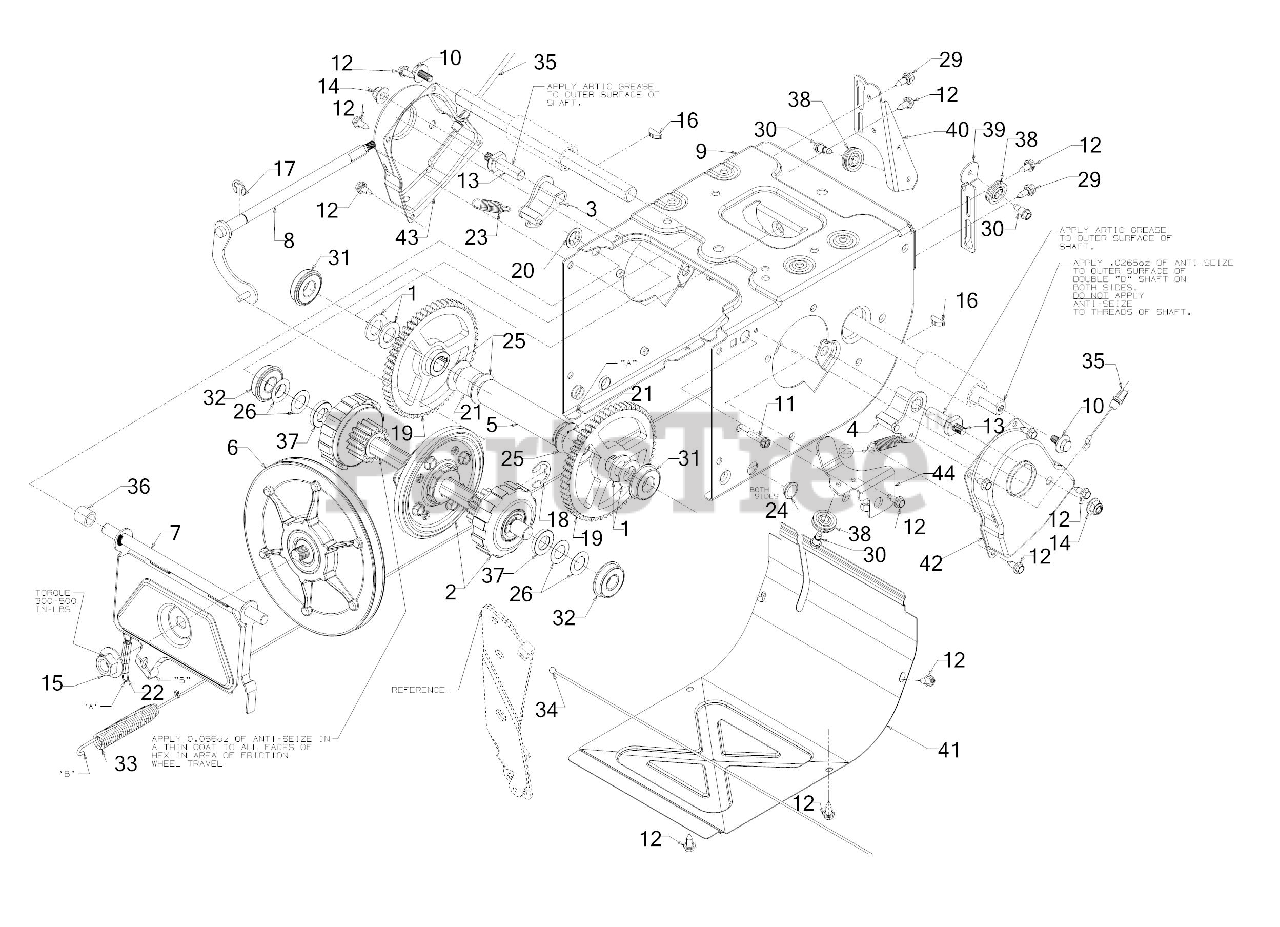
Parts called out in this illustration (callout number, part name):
1	WASHER .764X1.312X.091
2	PLANETARY SHIFT ASSEMBLY
2	SHIFT ASSEMBLY
2	FRICTION WHEEL ASSEMBLY
3	DOGG ASSEMBLY (RH)
4	DOGG ASSEMBLY (LH)
5	AXLE SUPPORT TUBE ASSEMBLY
6	FRICTION WHEEL DISC ASSEMBLY
7	FRICTION WHEEL BRACKET
8	SHIFT ROD ASSEMBLY
9	DRIVE FRAME
10	SCREW 5/16-24 x .750 GR5
11	SCREW 1/4-20 x 1.00
12	SCREW 1/4-20X.625
13	ACTUATOR SHAFT
15	FLANGE NUT 5/8-18
16	KEY 3/16 x 3/4
17	E-RING FOR .500
18	RETAINING RING
21	SPACER: .76ID x .75
22	EXTENSION SPRING
23	EXTENSION SPRING
25	FLAT WASHER .760ID X1.49OD x .06
26	FLAT WASHER .67X 1.174X .02
29	SHOULDER SCREW
30	SHOULDER SCREW
31	BALL BEARING
32	BALL BEARING
33	WHEEL DRIVE CABLE 44.955"
34	AUGER DRIVE CABLE 47.48"
35	STEERING CABLE
36	SPACER-.513 ID x .703 OD x .69
38	CABLE GUIDE ROLLER
39	AUGER CABLE GUIDE BRACKET
40	GUIDE BRACKET
42	STEERABLE DRIVE SHAFT RETAINER (LH)
43	STEERABLE DRIVE SHAFT RETAINER (RH)
44	AUGER CABLE BRACKET
